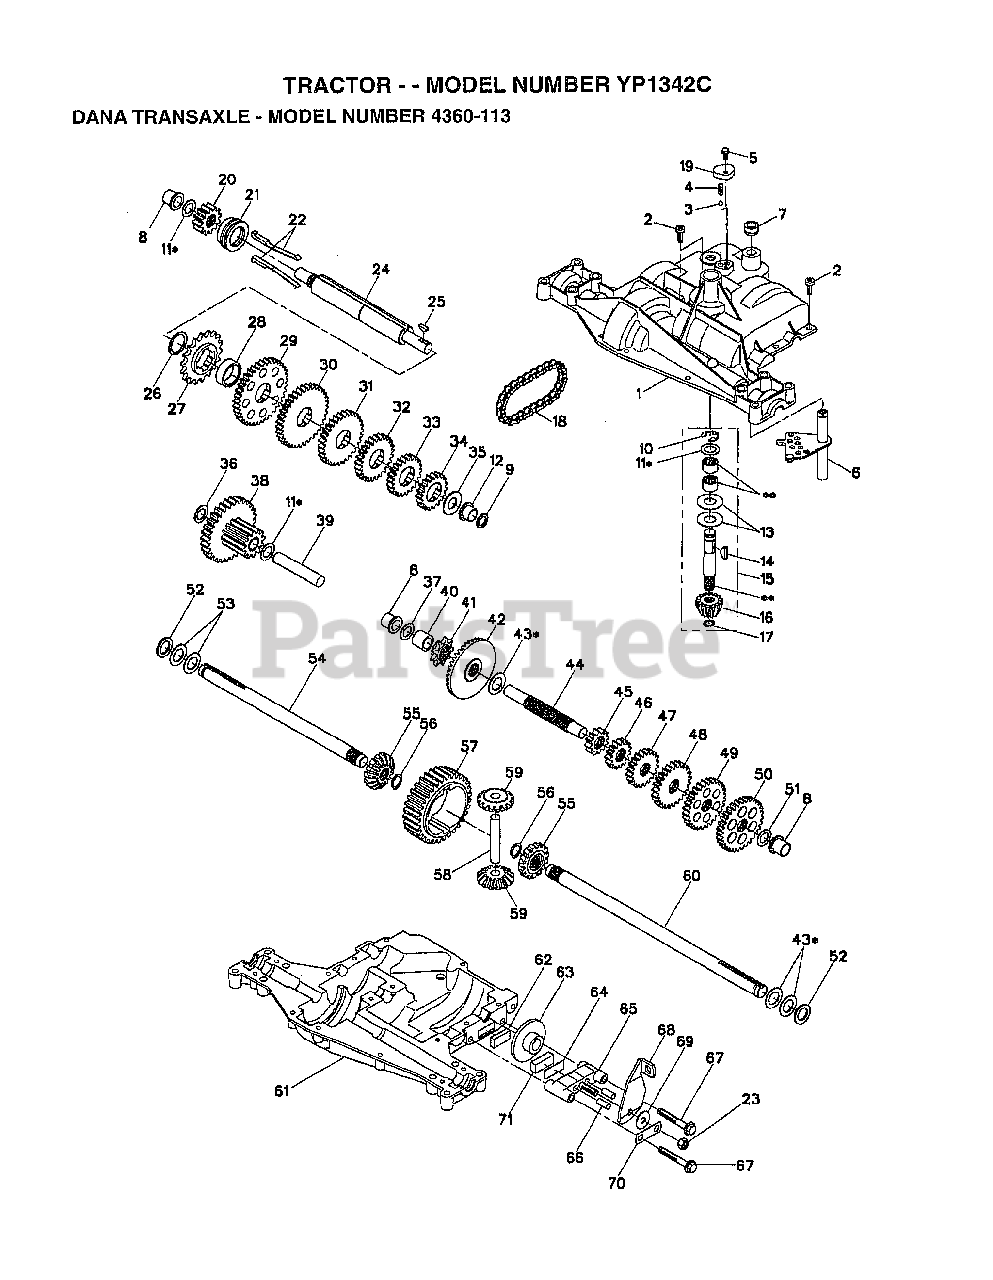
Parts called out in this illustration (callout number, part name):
1	HOUSING.UPPER.DANA.(5305J)
4	"SPRING, DETENT LT"
5	SCREW.TAPPING.1/4-20X.734
6	KIT SHIFTER ASM
9	SEAL.OIL.DAN.5508
10	RETAINING RING LT
11	ASM KIT SHIM 4689
12	BEARING.FLNG.5511
13	WASHER T
14	KEY WOODRUFF-DANA
15	AS KIT INPUT SHFT
16	PINION 14T T
17	"RING,RETAINING LT"
18	"CHAIN,24 PTCH LT"
19	COVER.DETENT.(5584)
20	GEAR.SPUR.12T.(5627)
21	CLUTCH.COL.5467
22	ASM KIT CLTCH KEY
23	NUT.LOCK.5/16-24
24	SHAFT INTERM DANA
25	WOODRUFF KEY
26	"RING,RETAINING LT"
27	SPROCKET 18T T
28	SPACER YT
29	GEAR SPUR 37 TTH
30	GEAR SPUR 35 TTH
31	GEAR SPUR 30T
32	GEAR 25T LT
33	GEAR SPUR 22 TT
34	SPUR GEAR 19T
35	"WASHER, PLAIN LT"
36	WASHER 045
37	WASHER 031
38	ASSY.GEAR.6153 12T&30T
39	SHAFT IDLER
40	SPACER T
41	SPROCKET 9T LT
43	ASM KIT SHIM
44	SHAFT T
45	GEAR SPUR 12 TTH
47	GEAR SPUR 20T
48	"GEAR, SPUR 25T LT"
49	GEAR 28T T
50	"GEAR, SPUR 31T LT"
51	WASHER 060
52	NEOPRENE WASHER
53	WASHER 031
54	AXLE.LH(5528-1)
55	GEAR 15T T
56	RING.RETAINING.(5270)
58	SHAFT T
59	GEAR 1ST T
60	AXLE.RH.(5528-2) DANA
61	HOUSING LOWER TNS
62	PUCK T
63	BRAKE DISC. T
64	SPACER LT
66	PIN T
67	SCREW.(5562) .5/16-18X2.35
69	WASHER LT
70	BRACKET, ANTI-ROTATION
71	PUCK T
